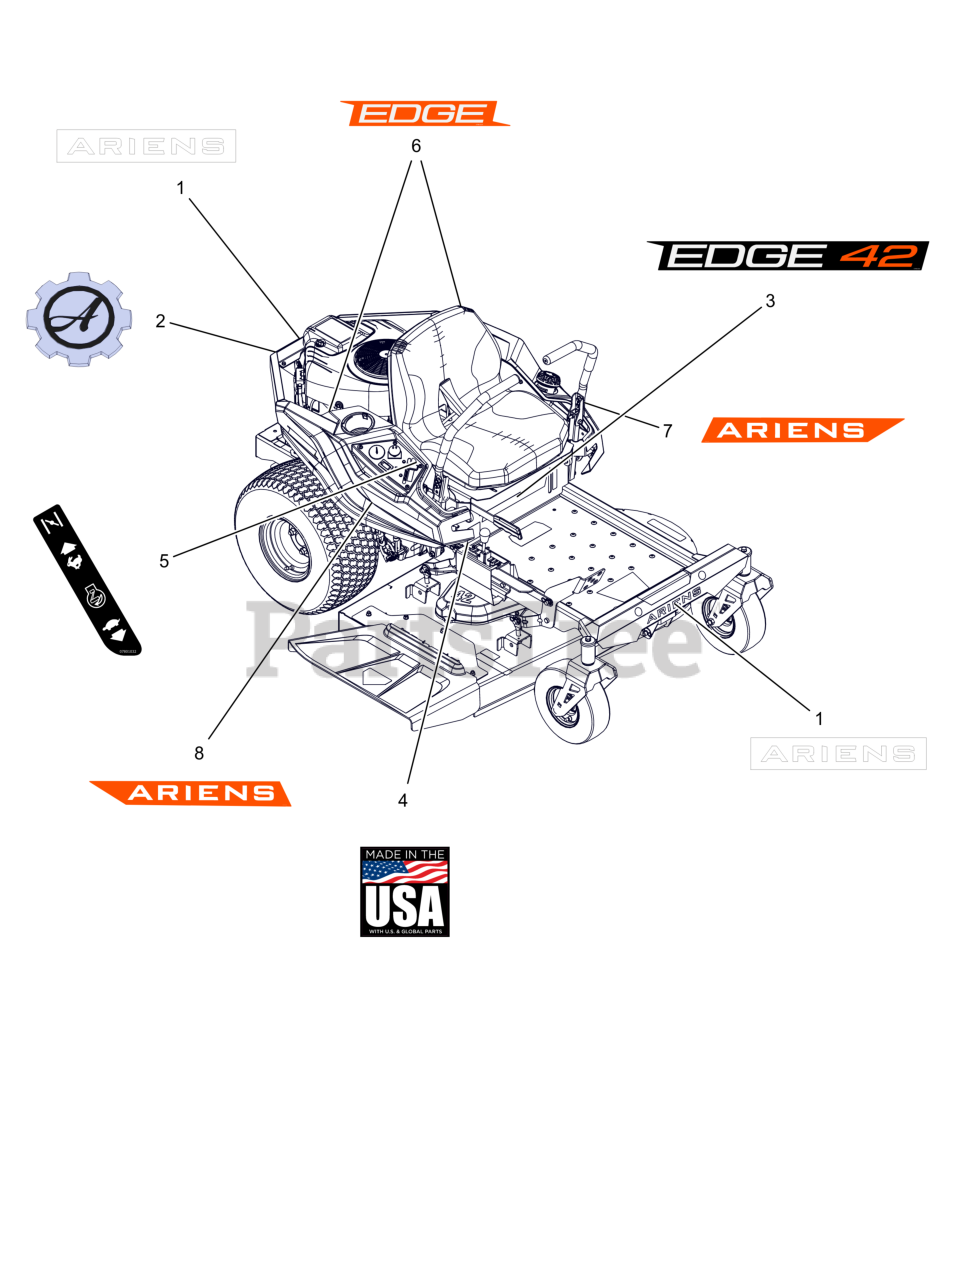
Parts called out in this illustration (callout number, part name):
1	DECAL - ARIENS 9.625"
2	DECAL, ARIENS-GEAR BADGE -THK
3	DECAL, EDGE 42 - KICKPLATE
4	DECAL, MADE IN USA
5	DECAL- SPEED CONTROL W/CHOKE
6	DECAL, EDGE FENDER
7	DECAL, ARIENS FENDER LH
8	DECAL, ARIENS FENDER RH
